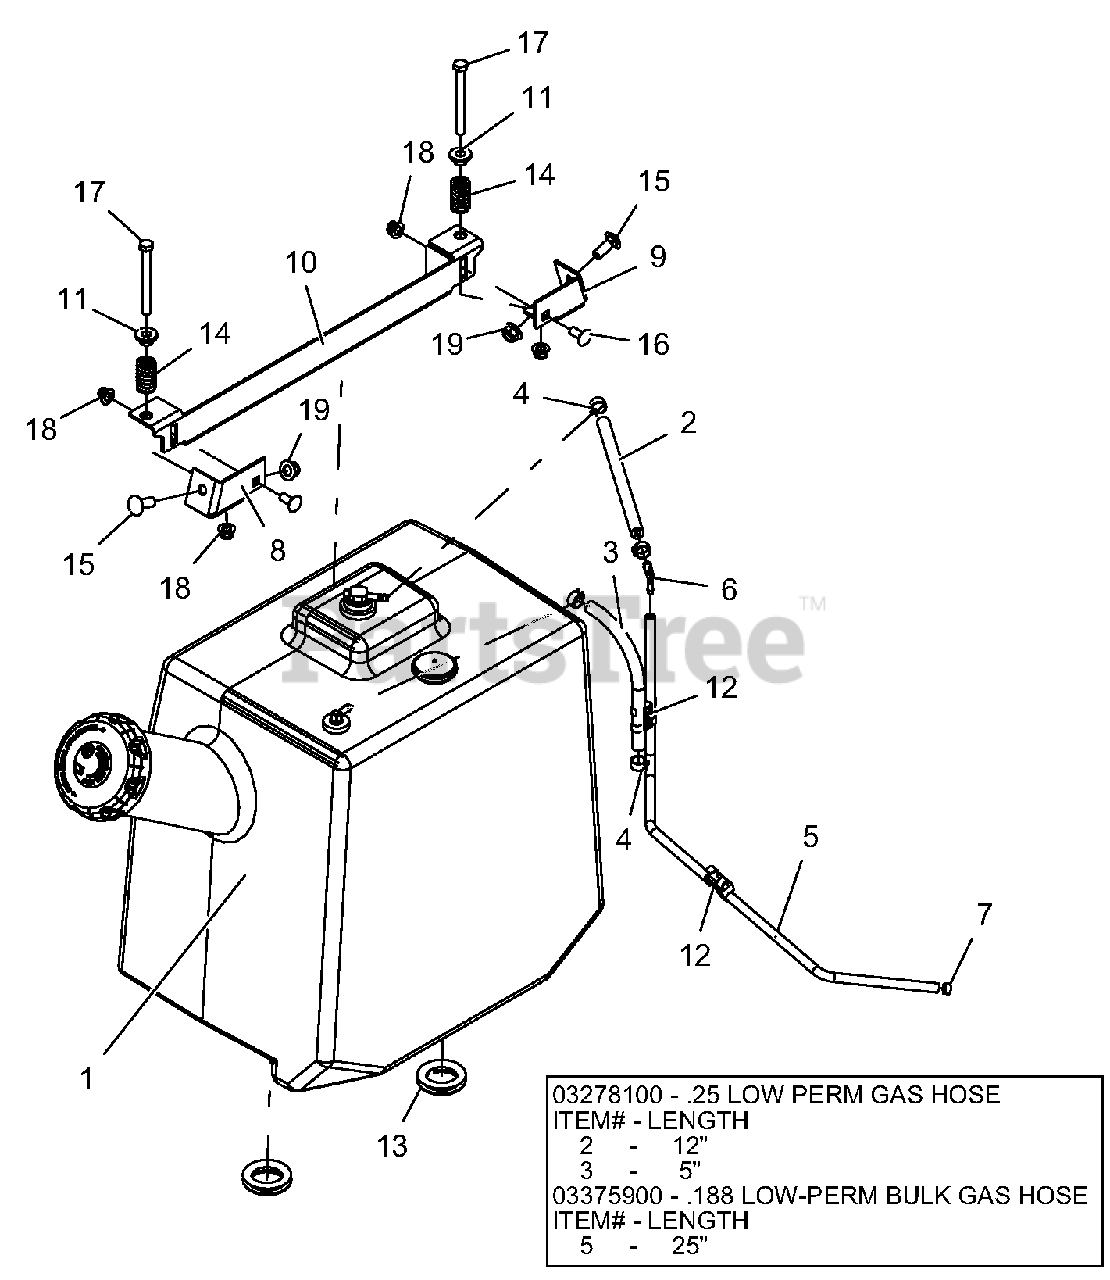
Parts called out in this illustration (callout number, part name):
1	ASSY, EPA PROSTANCE FUEL TANK
2	.25 LOW PERM GAS HOSE
3	.25 LOW PERM GAS HOSE
4	CLAMP, FUEL LINE
5	HOSE, .188 LOW-PERM BULK GAS
6	FITTING-3/16 x 1/4 90DEGREE VAC
7	CLAMP - HOSE, SPRING .188
8	WLDMT, TANK HOLDDOWN-RH
9	WLDMT, TANK HOLDDOWN-LH
10	HOLDDOWN, FUEL TANK
11	BSHG, FLG .385 x .500 x .875 x .406
12	CLIP, T, .38-.50
13	GROMMET, 1.25"
14	SPRG, COMPRESSION
15	BLT-RDHDSQNK .38-16 x 1.00 G5 YWZC
16	BLT-RDHDSQNK .31-18 x .75 G5 YWZC
17	BLT-HEX .31-18 x 3.25 GR5 YWZC
18	NUT-LK-NYL-FLG .31-18 YWZC
19	NUT-LK-NYL-FLG .38-16 YWZC
